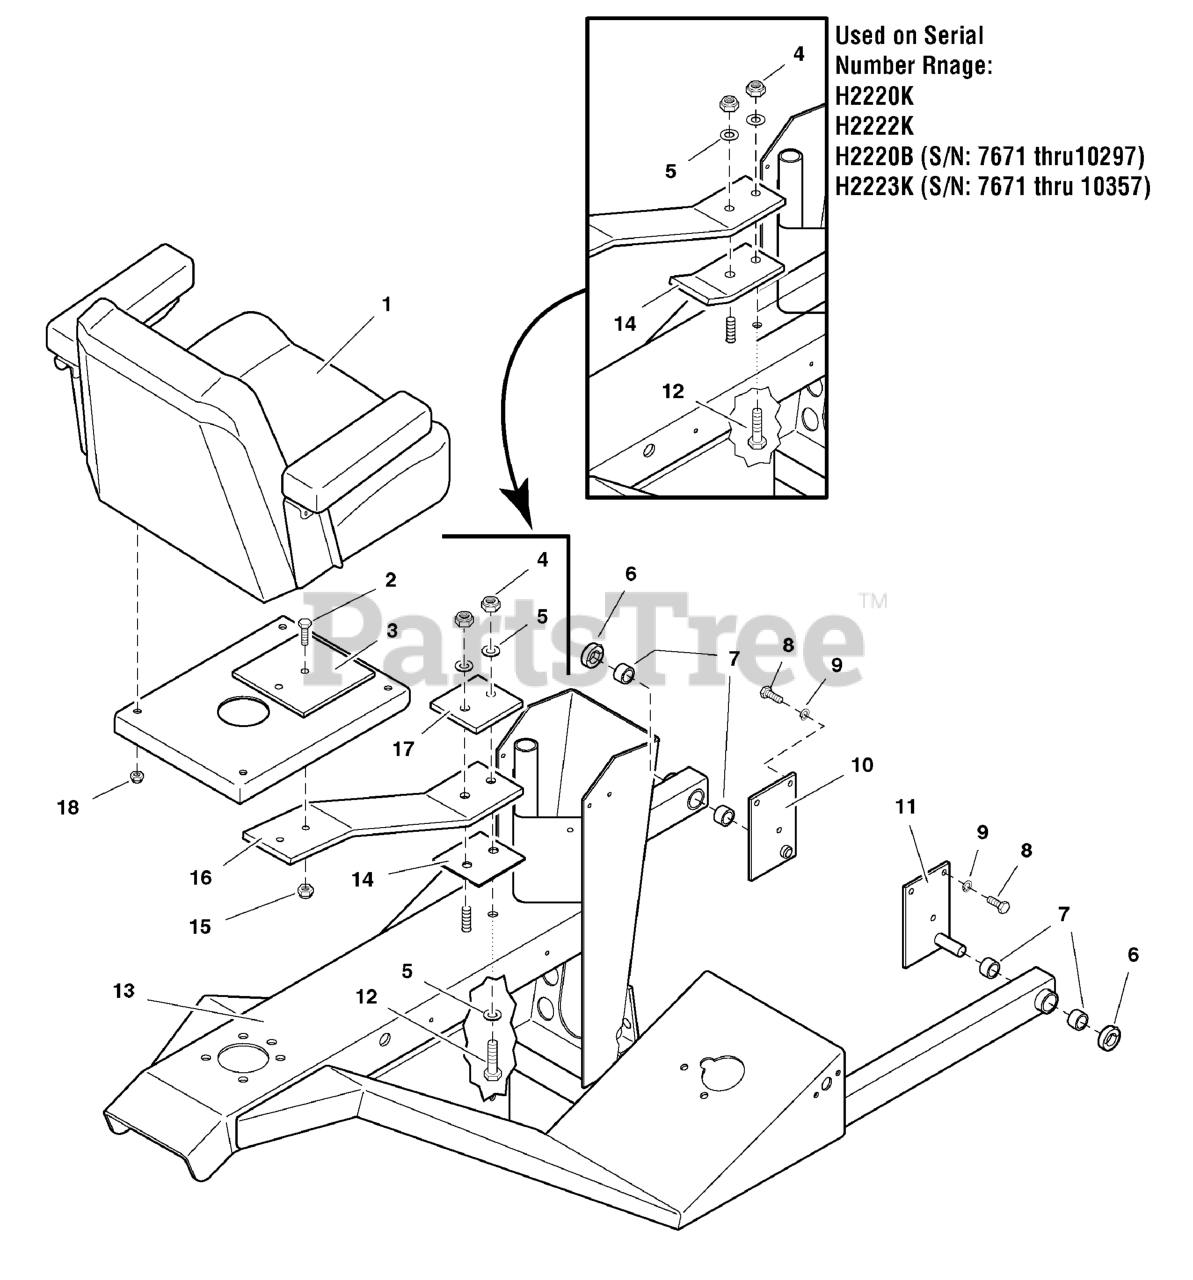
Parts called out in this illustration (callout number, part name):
1	SEAT, GRAY, NO LOGO, CMPT
1	SEAT BOTTOM (EVC 907)
1	CUSHION, Back, Gray
1	ARM REST, BLACK MOLDED, PAD ONLY
1	SEAT ADJUSTER RAILS (set of 2)
2	BOLT, 3/8-16 X 1-1/4" GD5 CZ
3	PLATE, Seat Mount
4	NUT, 7/16-20 Hex Nylon Lock
5	WASHER, 7/16" GD9
5	WASHER, 7/16" SAE
6	COLLAR, 5/8" Set
7	BUSHING, Plastic
8	BOLT, 5/16-18 X 1 GD5 YZ
9	WASHER, 5/16 LOCK CZ
10	WELD, BRACKET, PIVOT - LEFT
11	WELD, BRACKET, PIVOT - RIGHT
12	BOLT, 7/16-20 x 2
12	BOLT, 7/16-20 x 1-3/4
13	TRAILER FRAME
14	SHIM, Seat Spring, Lower
14	SUPPORT, Seat Spring
15	NUT, 3/8-16 HEX NYLON LOCK
16	SEAT SPRING
17	SHIM, Seat Spring, Upper
18	NUT, 5/16-18 Hex Nylon Lock
19	SPRING, EXTENSION, SEAT ADJUSTMENT (YEL OR BLK)
